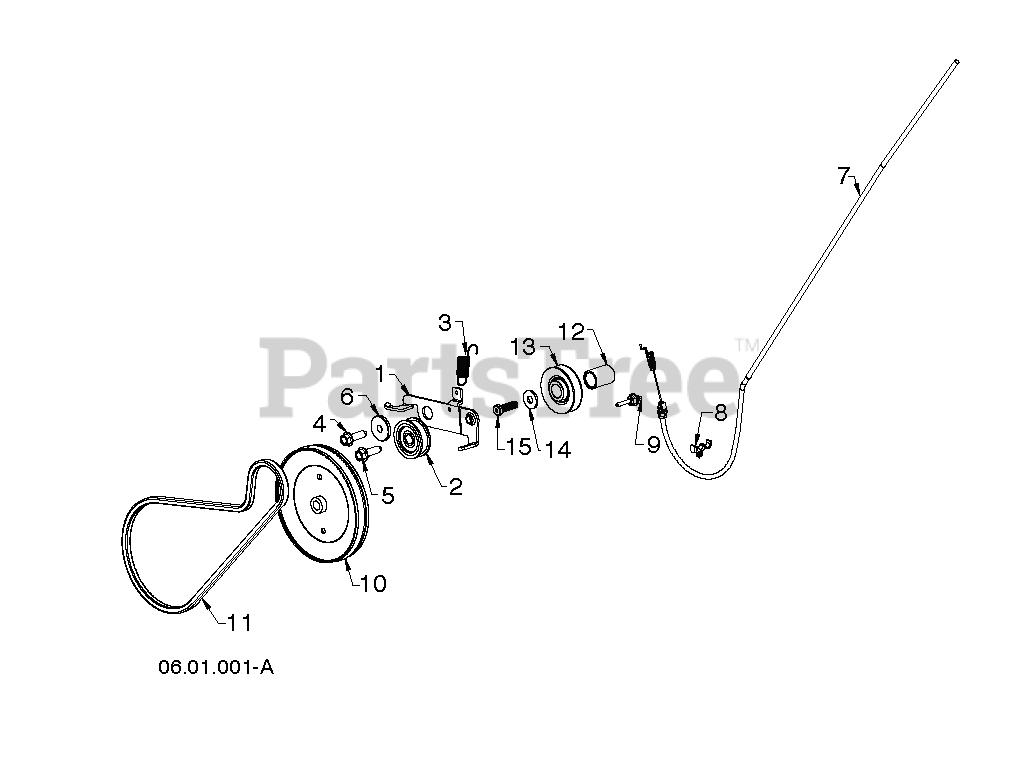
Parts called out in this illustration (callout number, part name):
1	ARM.IDLER.SINGLE.STAGE.SNOW.BL
2	IDLER PULLEY
3	SPRING.EIDLER.PULLEY.RETURN
4	SCREW.3/8-16
5	SCREW.3/8-16
6	SPACER.RETAINER
7	CABLE.CLUTCH.SSST.SHORT
9	KEEPER.ENGINE.BELT
10	PULLEY.DRIVEN
11	BELT.4L.1/2X35
12	SPACER.ENGINE.CRANK
13	PULLEY.ENG.TRACTION
14	WASHER,HARDEN
15	BOLT, SCKT HD 3/8-24 X 1 .25
